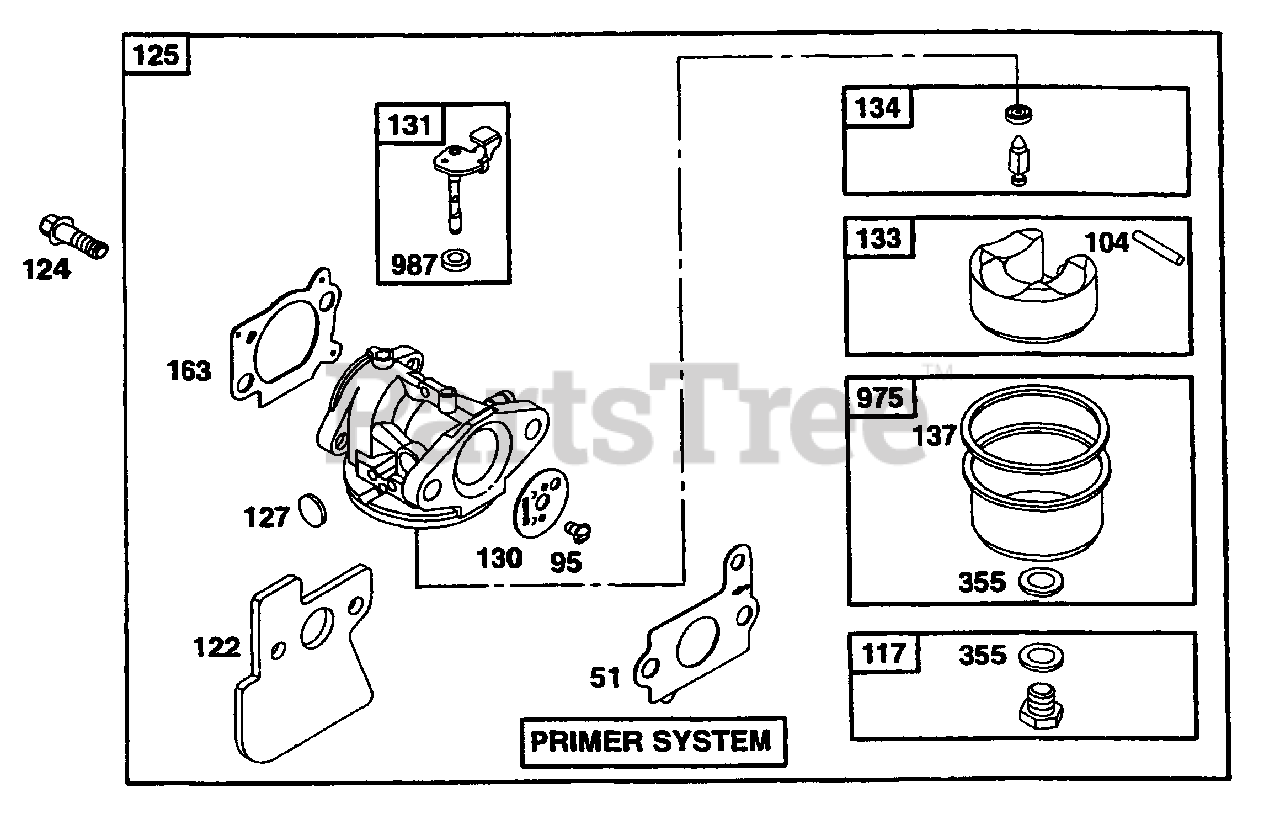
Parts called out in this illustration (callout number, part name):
51	Intake Gasket
95	Round Head Screw
104	Float Pin
122	Carburetor Spacer
124	Screw Hex
125	Carburetor
127	Welch Plug
130	Throttle Valve
131	Throttle Shaft
134	Needle Valve
137	Float Bowl Gasket
163	Air Cleaner Gasket
355	Seal Washer
975	Float Bowl
987	Throttle Shaft Seal
